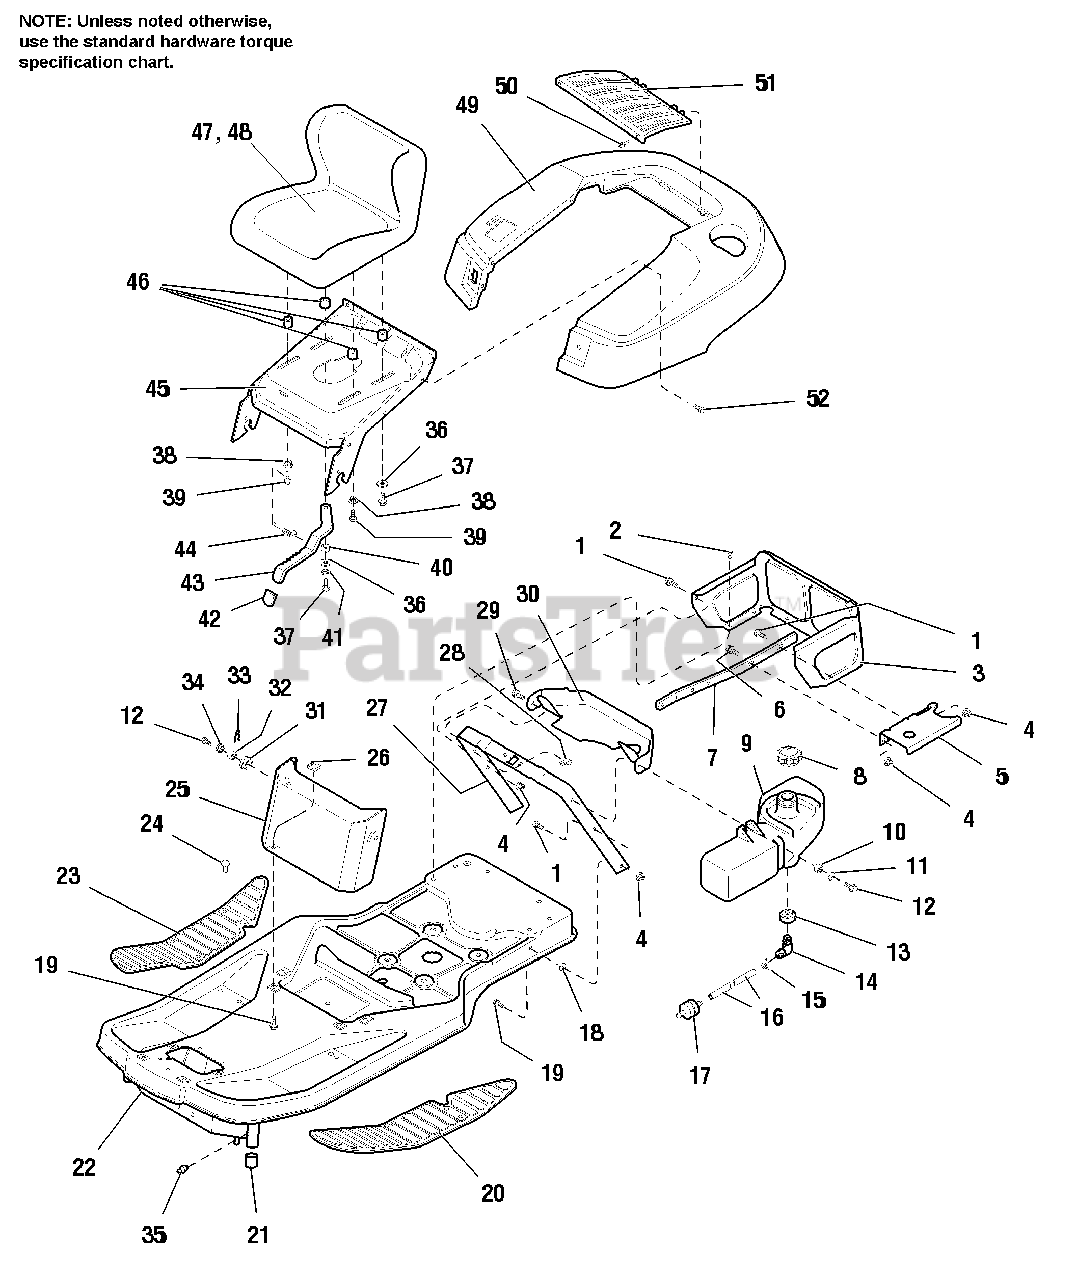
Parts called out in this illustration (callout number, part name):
1	CAPSCREW, Hex Hd., 5/16-18 x 1
2	SCREW, Hex Hd., Taptite, 1/4-20 x 1/2
3	SHROUD, Rear
4	NUT, Hex, Flange, Whizlock, 5/16-18
5	SUPPORT, Fuel Tank
6	CARRIAGE BOLT, 5/16-18 x 3/4
7	STRAP, Fuel Tank, Brace
8	CAP, Fuel Tank, Vented
9	FUEL TANK
10	SPACER, 21/64 x 1/2 x 21/64
11	WASHER, Plain, 13/32 x 7/8 x 5/64
12	SCREW, Taptite, 5/16-18 x 1
13	BUSHING, Rubber
15	CLAMP, Hose
16	HOSE, Fuel Tank
17	FUEL FILTER
18	PAL NUT, 5/16
19	CAPSCREW, Hex Hd., Whizlock, 5/16-18 x 3/4
20	PAD, Foot Rest, LH
22	FRAME ASSY.
23	PAD, Foot Rest, RH
25	PANEL, Front
26	PAL NUT, 5/16-18
27	"U" SUPPORT, Seat Deck
28	CLIP
29	SCREW, Hex Hd., Taptite, 5/16 x 1/2
30	DUCT, Air Inlet
31	SPACER, Plastic
34	PIVOT, Hood
35	FITTING, Lube
36	WASHER, 5/16
37	CAPSCREW, 5/16-18 x 3/4
38	NUT, Flange, 5/16-18
39	CAPSCREW, Hex Hd., 5/16-18
41	LOCKWASHER, Spring
42	CAP, Black, Vinyl
43	ADJUSTER, Seat
44	SPRING, Extension
45	SUPPORT, Slide, Seat
47	SEAT ASSY.
48	COVER, Seat, Black
49	DECK, Seat, Orange
49	DECK, Seat, Red
51	SCREEN, Seat Deck Top
52	SCREW, Hex Whiz Lock
